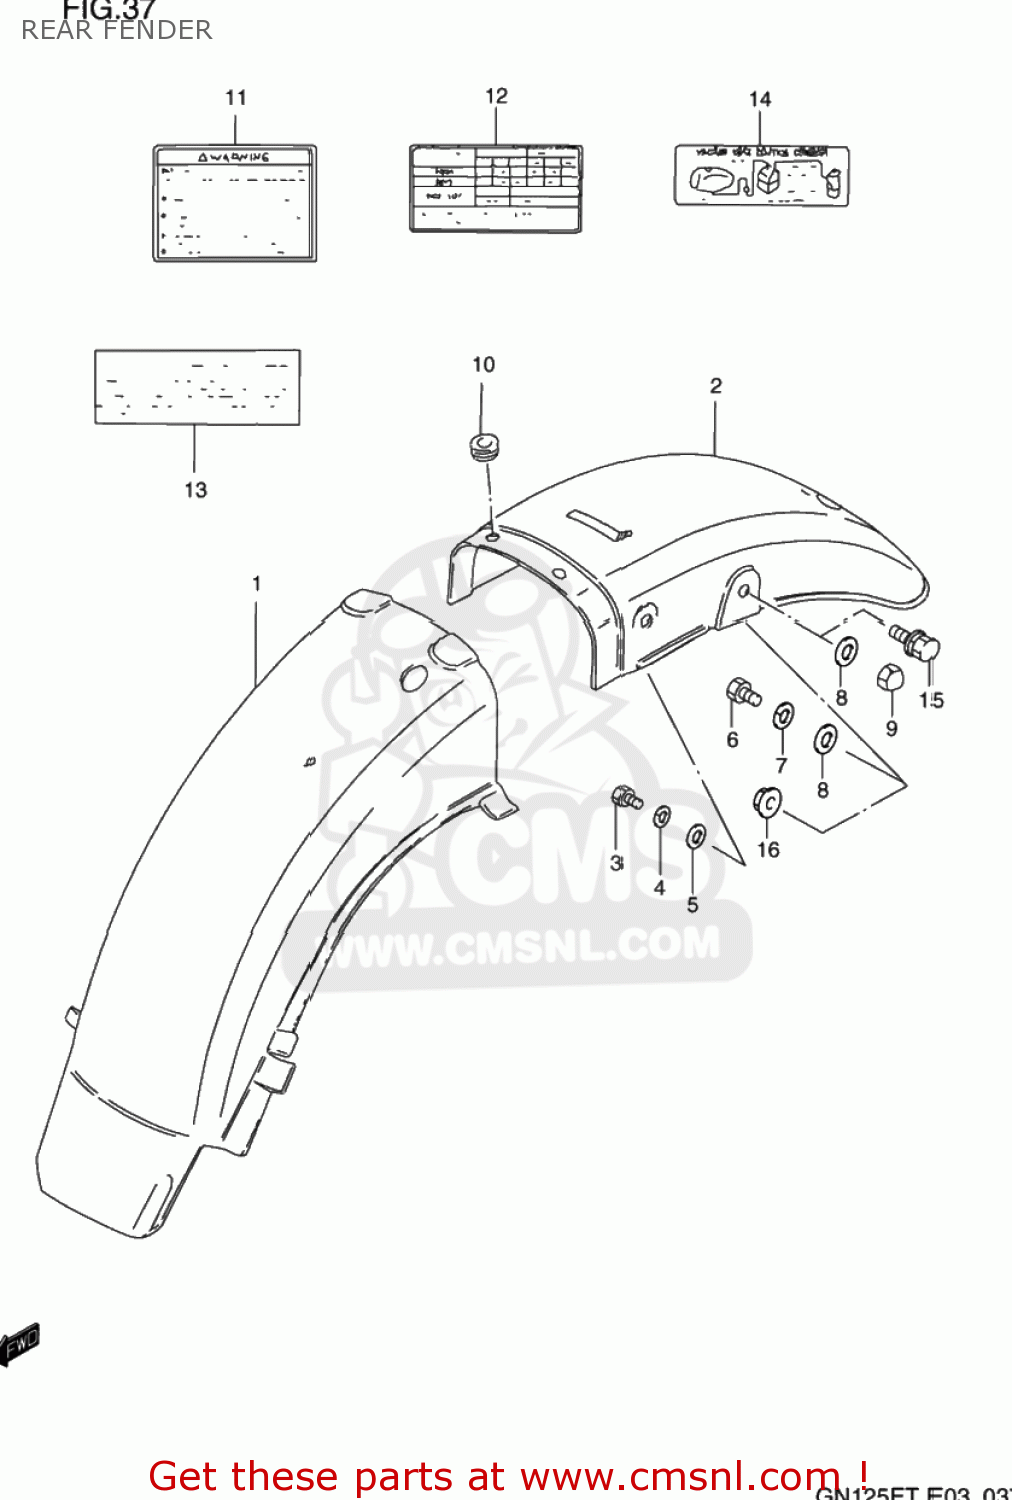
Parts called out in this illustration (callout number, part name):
1	BODY,FR
2	FENDER,REAR FENDER,REAR
3	BOLT
4	WASHER,LOCK
5	WASHER
6	BOLT
7	WASHER,LOCK
8	WASHER
9	NUT
10	CUSHION
11	LABEL
12	LABEL (TIRE AIR PRESSURE)
13	LABEL (MANUAL NOTICE)
14	LABEL (PIPING DIAGRAM)
15	BOLT
16	NUT
17	MANUAL, OWNER'S
